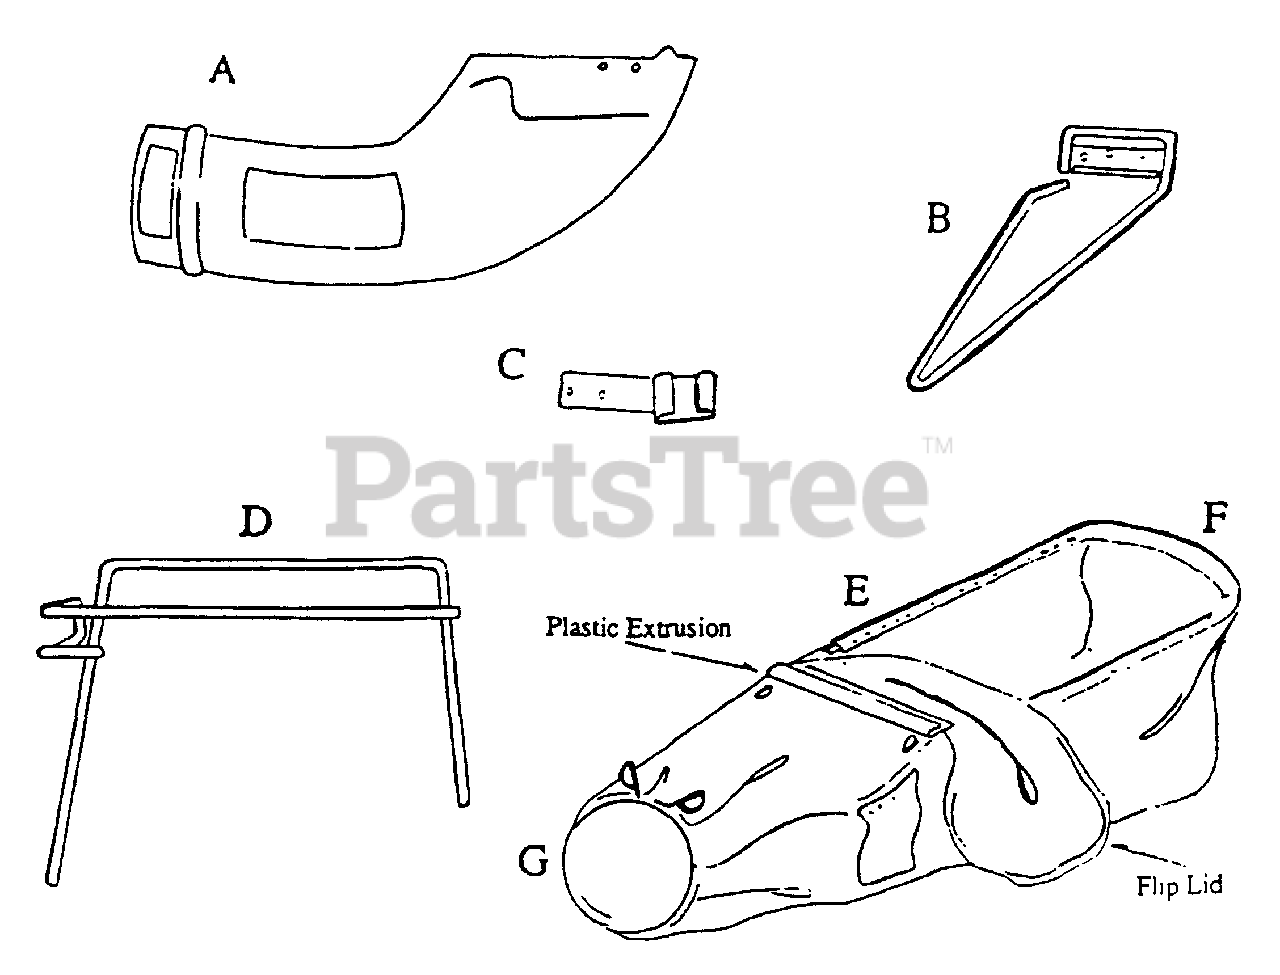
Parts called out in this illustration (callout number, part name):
A	Plastic Chute
B	Chute Mounting Bracket with Wire
C	Handle Bracket
D	Bag Frame
E	Bag
F	Hairpin
G	Clamp Ring
H	1/4-20 x 1/2" THMS
I	1/4-20 Locknut
